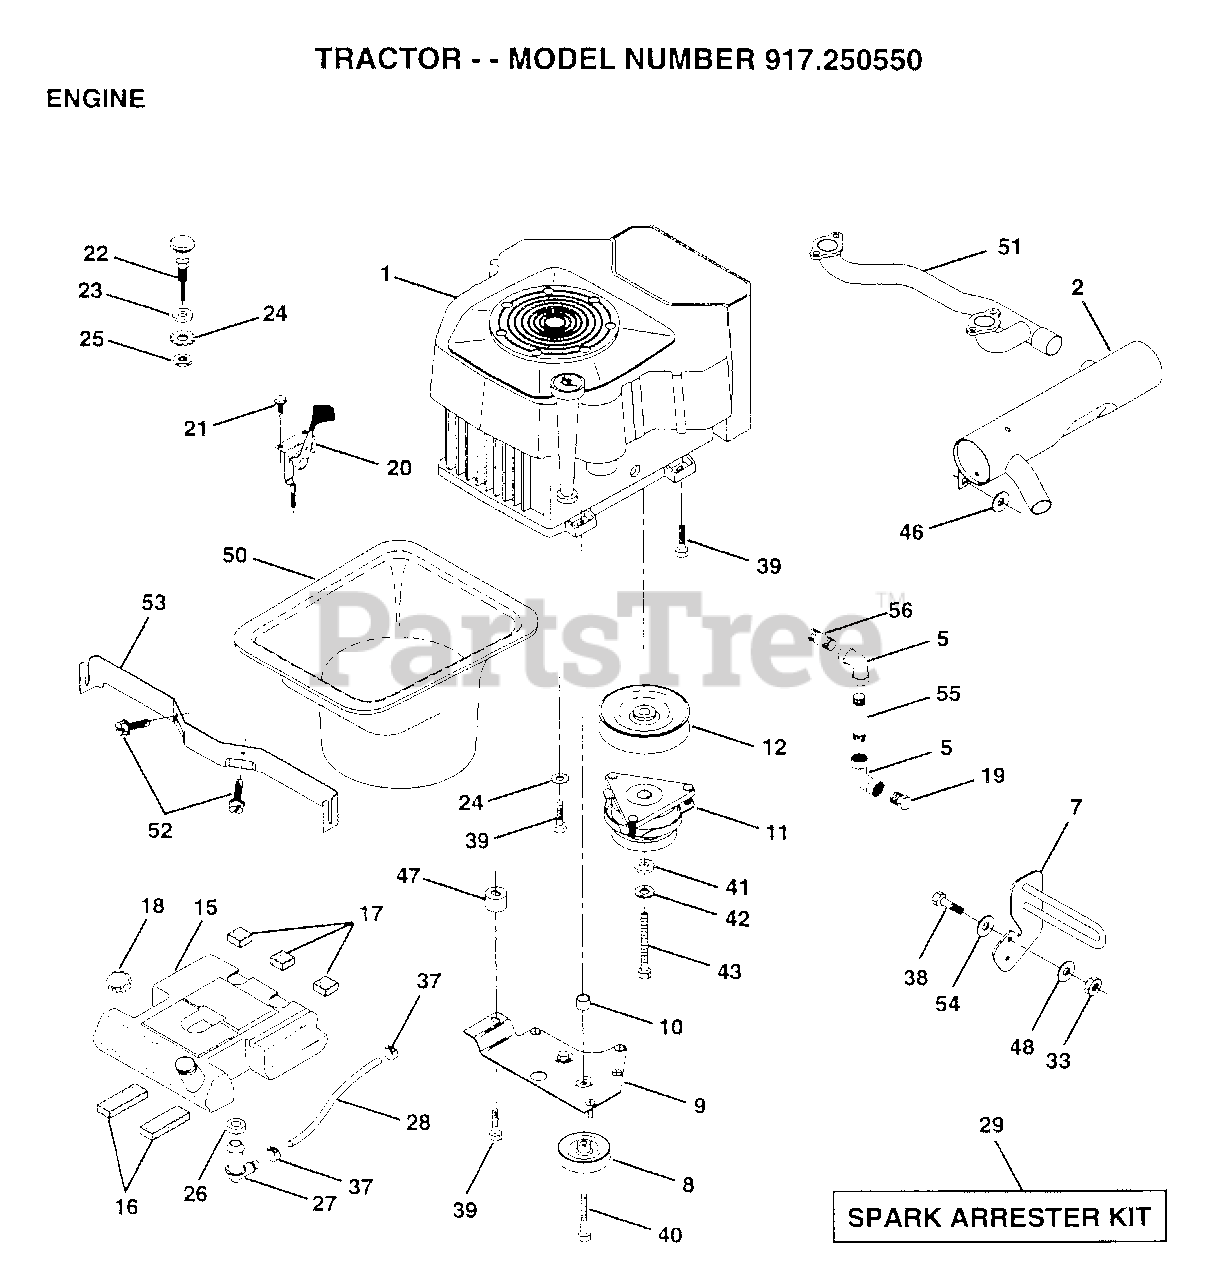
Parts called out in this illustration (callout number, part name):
5	ELBOW
10	BUSHING.
12	PULLEY.ENG.CLUTCH
16	PAD IDLER TI
17	PAD-SPACER LT
19	PLUG T
21	SCREW LT
22	CHOKE CONTROL
23	WASHER
24	LOCKWASHER
26	BUSHING OUTLET T
27	STEM.TANK.FUEL
29	SPARK ARREST KIT
33	NUT
37	HOSE CLAMP
38	"BOLT,HEX"
39	SCREW.3/8-16X2.25
40	SCREW.TT.3/8-16X4
41	WASHER
42	LOCKWASHER
46	WASHER HYT
47	SPACER.ENGINE
48	WASHER T
50	DUCT.AIR.VGT
52	SCREW CRT
53	BRACKET.DUCT.AIR
54	WASHER
56	NIPPLE.PIPE
